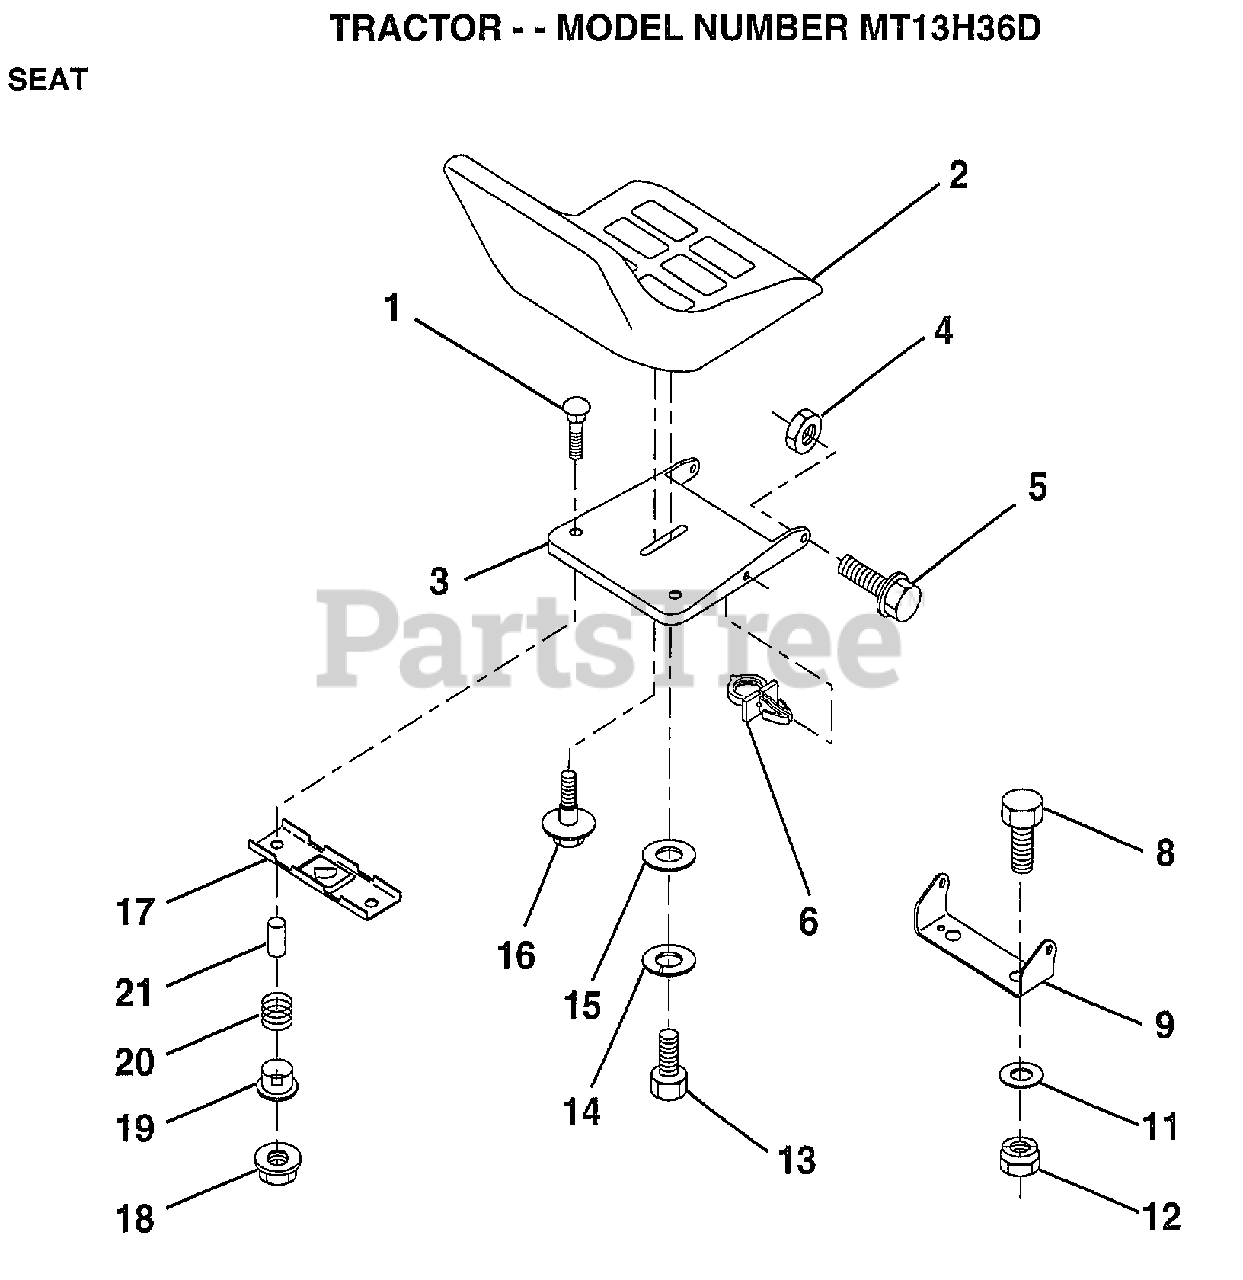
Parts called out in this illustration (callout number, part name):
1	BOLT-RD HD SQ NK
2	SEAT.2400/1416.BK
3	PAN-SEAT
4	NUT
5	"BOLT,SHOULDER"
6	CLIP.PUSH-IN.HING
8	BOLT
9	BRACKET PVT SEAT
11	WASHER
12	NUT
13	BOLT
14	LOCKWASHER
15	WASHER
16	"BOLT,SHOULDER"
17	BRKT SWITCH
19	BUSHING
20	SPRING
21	SPLIT SPACER
